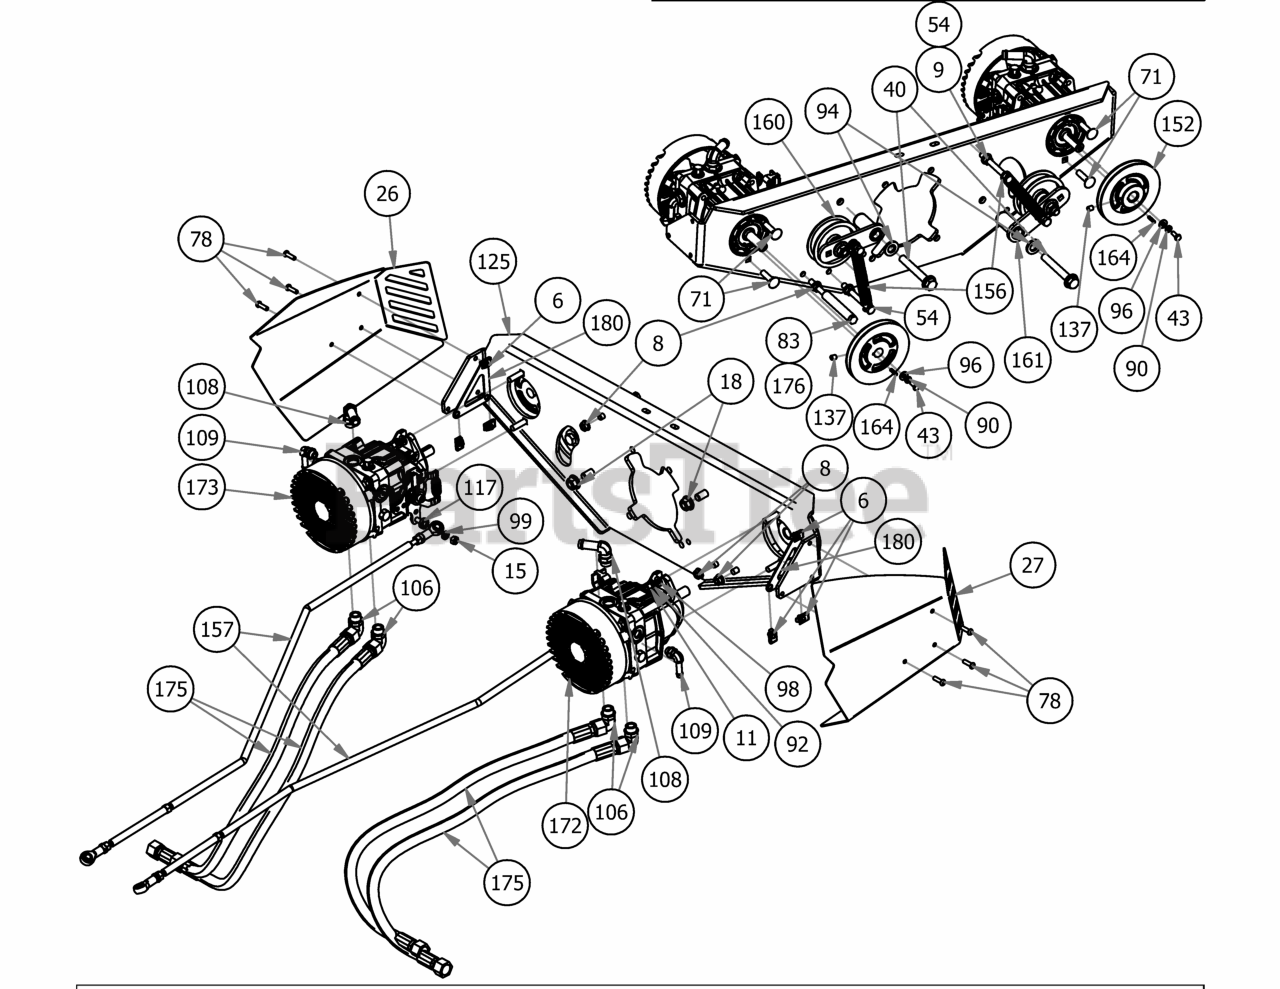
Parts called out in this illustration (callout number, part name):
6	1/4-20 Cage Nut
8	3/8-16 HEX SERRATED FLANGE NUT HARD/ZINC
9	3/8-16 NYLON INSERT FLANGE LOCKNUT (GR.F) ZINC
11	3/8" Hex Nut
18	1/2-13 NYLON INSERT FLANGE LOCKNUT ZINC
26	2019 Horizontal Pump Cover - Right
27	2019 Horizontal Pump Cover - Left
40	1/2-13 X 90MM HEX FLANGE BOLT W/SHOULDER (GR.8) ZINC
43	M6-1.0 X 16MM Hex Bolt
54	3/8-16 X 3-1/2 HEX CAP SCREW (GR.5) ZINC
57	5/16 x 1 1/4 Hex Bolt
71	3/8 x 1 1/2 Carriage Bolt
78	Hexagon Socket Button Head Cap Screw
83	3/8-16 x 5 1/2 Hex Bolt
90	1/4" Lock Washer
92	3/8" Lock Washer
94	.635 ID X 1.120 OD X .140 THICK FLAT WASHER NYLON
96	1/4" Flat Washer
98	5/16" Flat Washer
99	5/16" Lock Washer
106	2019 Outlaw 90 Degree Pump Fitting #6801-10-08
108	90 Degree Fitting, 1/2 x 3/4, 4601-8-8
109	90 Degree Fitting, 3/8 s 9/16
117	ACS Spacer 3/4x3/8x1/4
125	Pump Plate - 2019 Horizontal Gas
137	5/16-24 X 3/8 Set Screw
152	5" Pump Pulley
156	ZT and ACS Handle Spring
157	2019 Outlaw Gen2 Horizontal Push Rod Assembly
160	2019 Renegade Belt Tensioner LH
161	2019 Renegade Belt Tensioner LH
164	5mm x 1.25" Key
172	2019 Rogue/Renegade Left Pump 16cc
173	2019 Outlaw Renegade Right Pump 16cc
175	2019 Renegade Hydro Hose
176	3/8 hose 4" long
180	Pump Plate Clip Nut Holder
